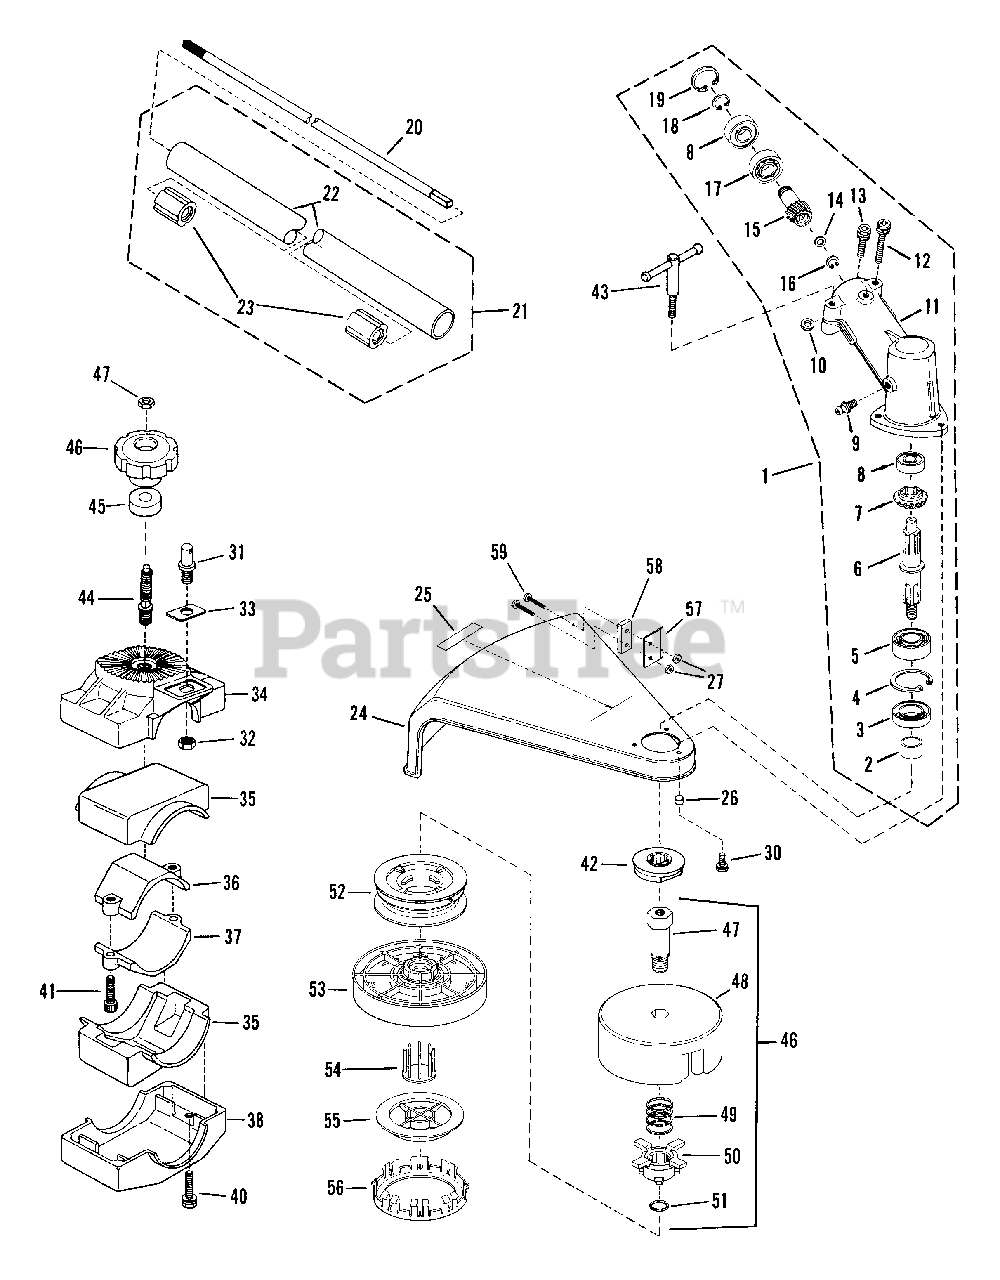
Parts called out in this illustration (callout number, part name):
1	ASSEMBLY, Gear Head
2	SLEEVE, Spline
3	SEAL, Oil
4	RING, Snap 35mm
5	BEARING
6	SHAFT, Spline
7	GEAR, Bevel
8	BEARING
9	FITTING, Lube
11	CASE, Gear
12	BOLT, M5 x 25mm Hex Head
13	BOLT, M5 x 12mm Hex Head
14	WASHER, Flat
15	PINION, Bevel
16	RING, Snap 10mm
17	BEARING
18	RING, Snap 10mm
19	RING, Snap 26mm
20	SHAFT, 1/4 Drive
21	ASSEMBLY, Tube & Bushing
22	TUBE, Main
23	BUSHING
24	ASSEMBLY, Plastic Shield
25	LABEL, Shield
26	SPACER, 5M
27	LOCKNUT, #10-32
28	KNOB, Torque
29	NUT, Self-Threader
30	SCREW, M5 x 16mm Hex
31	PIN, Guide
32	NUT,3/8-24 Hex Flange Lock
33	PLATE, Mounting Pin
34	SPACER, Knob
35	RUBBER, Vibro
36	CLAMP "A", Tube
37	CLAMP "B", Tube
38	JOINT "C", Handle
39	JOINT "D", Handle
40	SCREW, M6 x 30mm, Cross Hex Head
41	SCREW, M5 x 20mm, Socket Hex Head
42	SPACER, Blade
43	T-BOLT, M5
44	BOLT, Latch
45	SPACER, Knob
46	ASSM'Y, Housing
48	HOUSING
50	INDEXER
51	RETAINER, Wire
54	ACTUATOR
56	RETAINER, Knob
57	ASSM'Y, Line Cutter
58	BLOCK, Line Cuttter Mounting
59	SCREW, #10-32x7/8"
